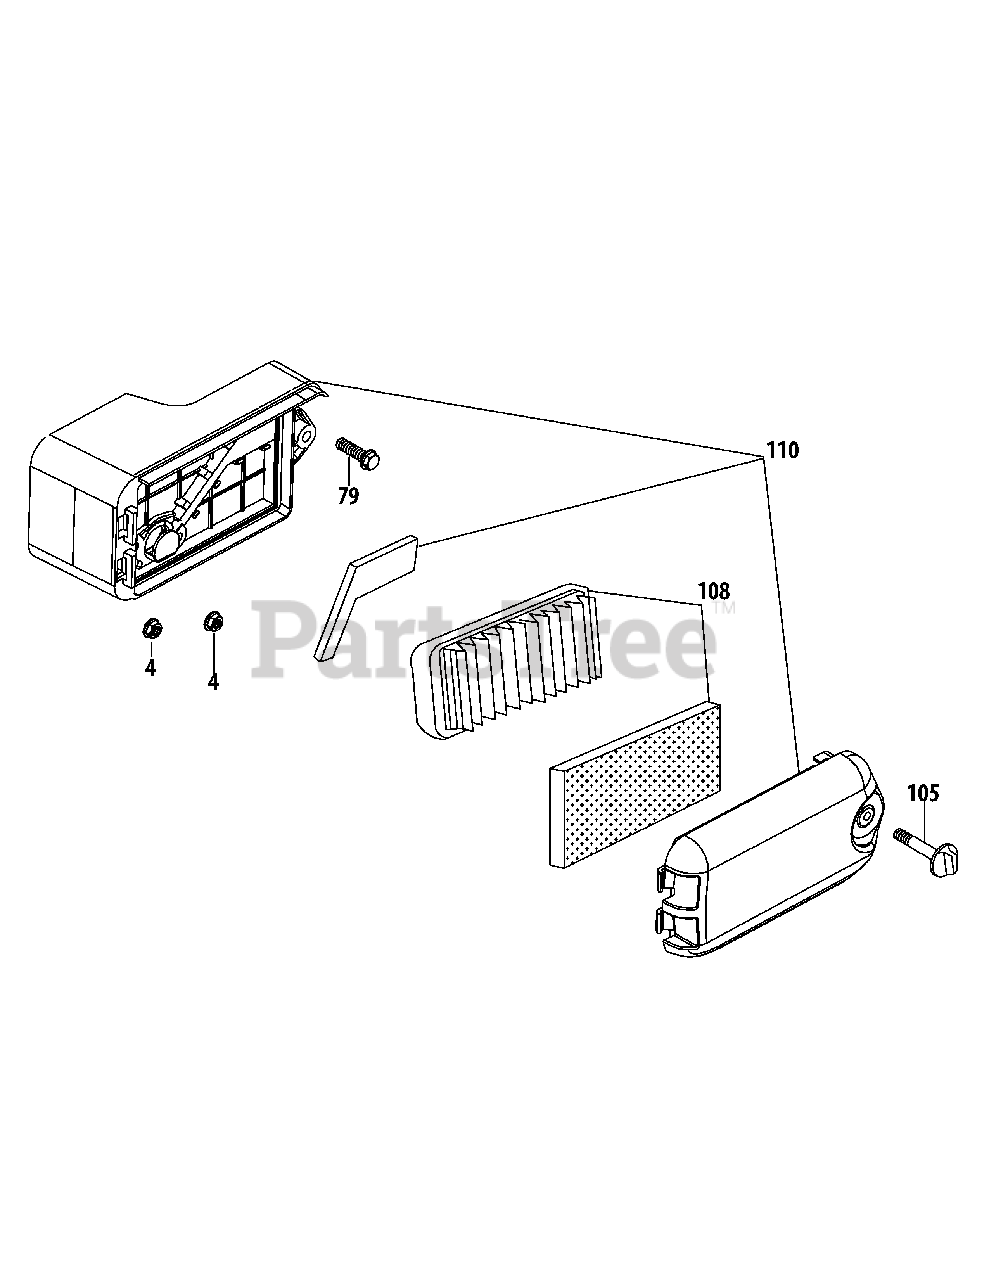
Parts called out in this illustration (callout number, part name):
4	Nut M6X10Mm
79	Bolt M6X35
105	Air Filter Cover Thumb Screw
108	Air Cleaner Kit
110	Air Cleaner Housing Ass'Y
